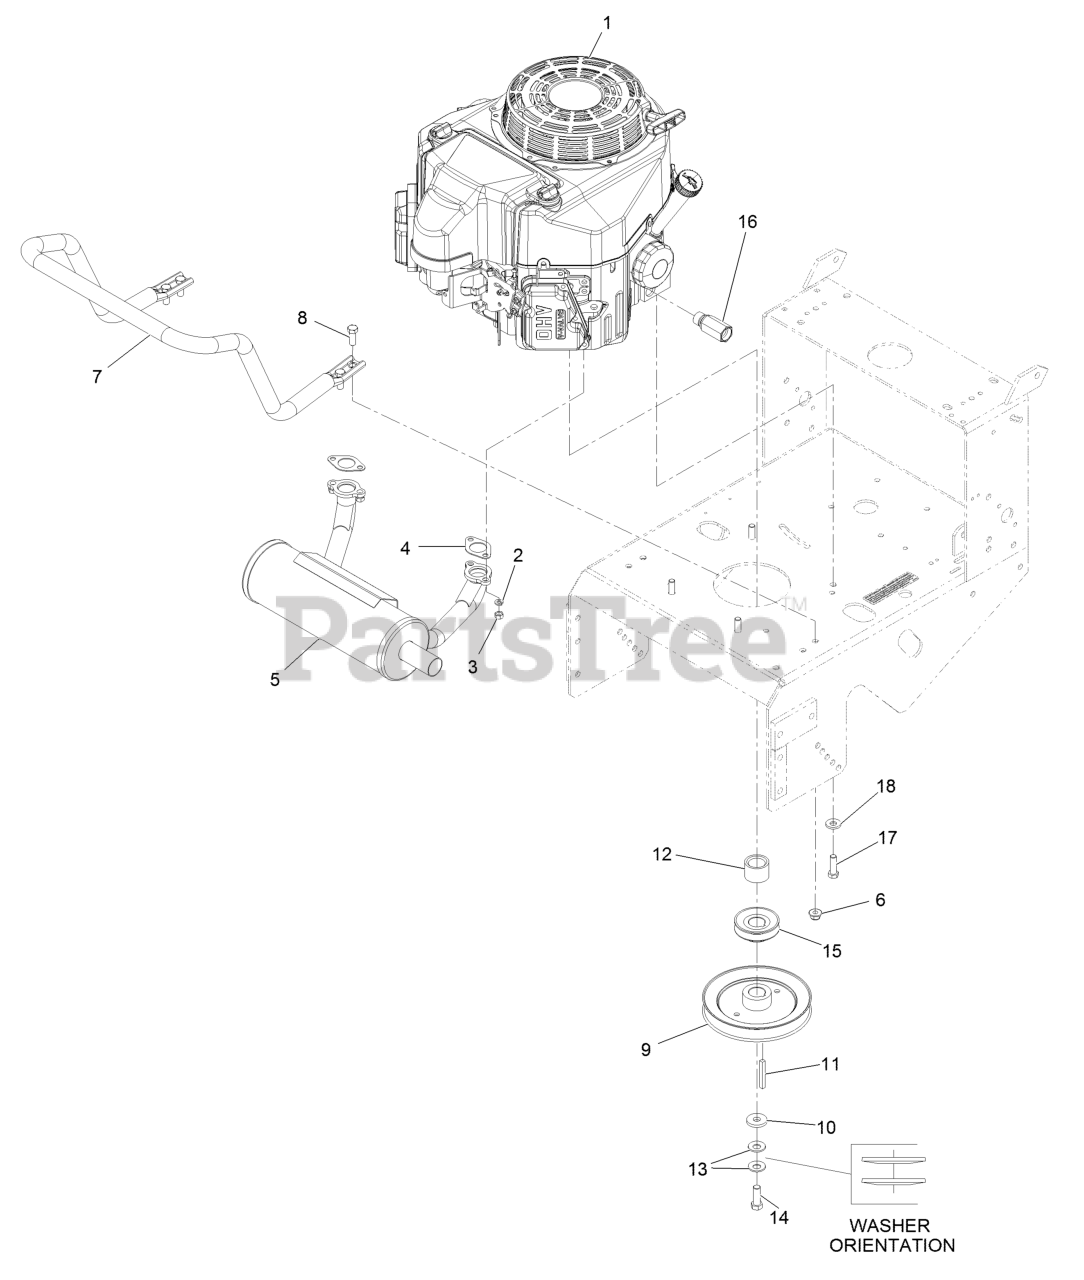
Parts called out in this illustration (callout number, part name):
1	Engine-Kawasaki
2	WASHER-LOCK
4	GASKET-EXHAUST
5	MUFFLER-HORIZONTAL, OFFSE
6	NUT-HF, NI
7	GUARD-MUFFLER
8	SCREW-HH
12	SPACER-CLUTCH
13	WASHER-SPRING
14	SCREW-HH
15	SHEAVE-TRANSMISSION
16	ADAPTER
17	SCREW-HH
18	WASHER-BELLEVILLE
